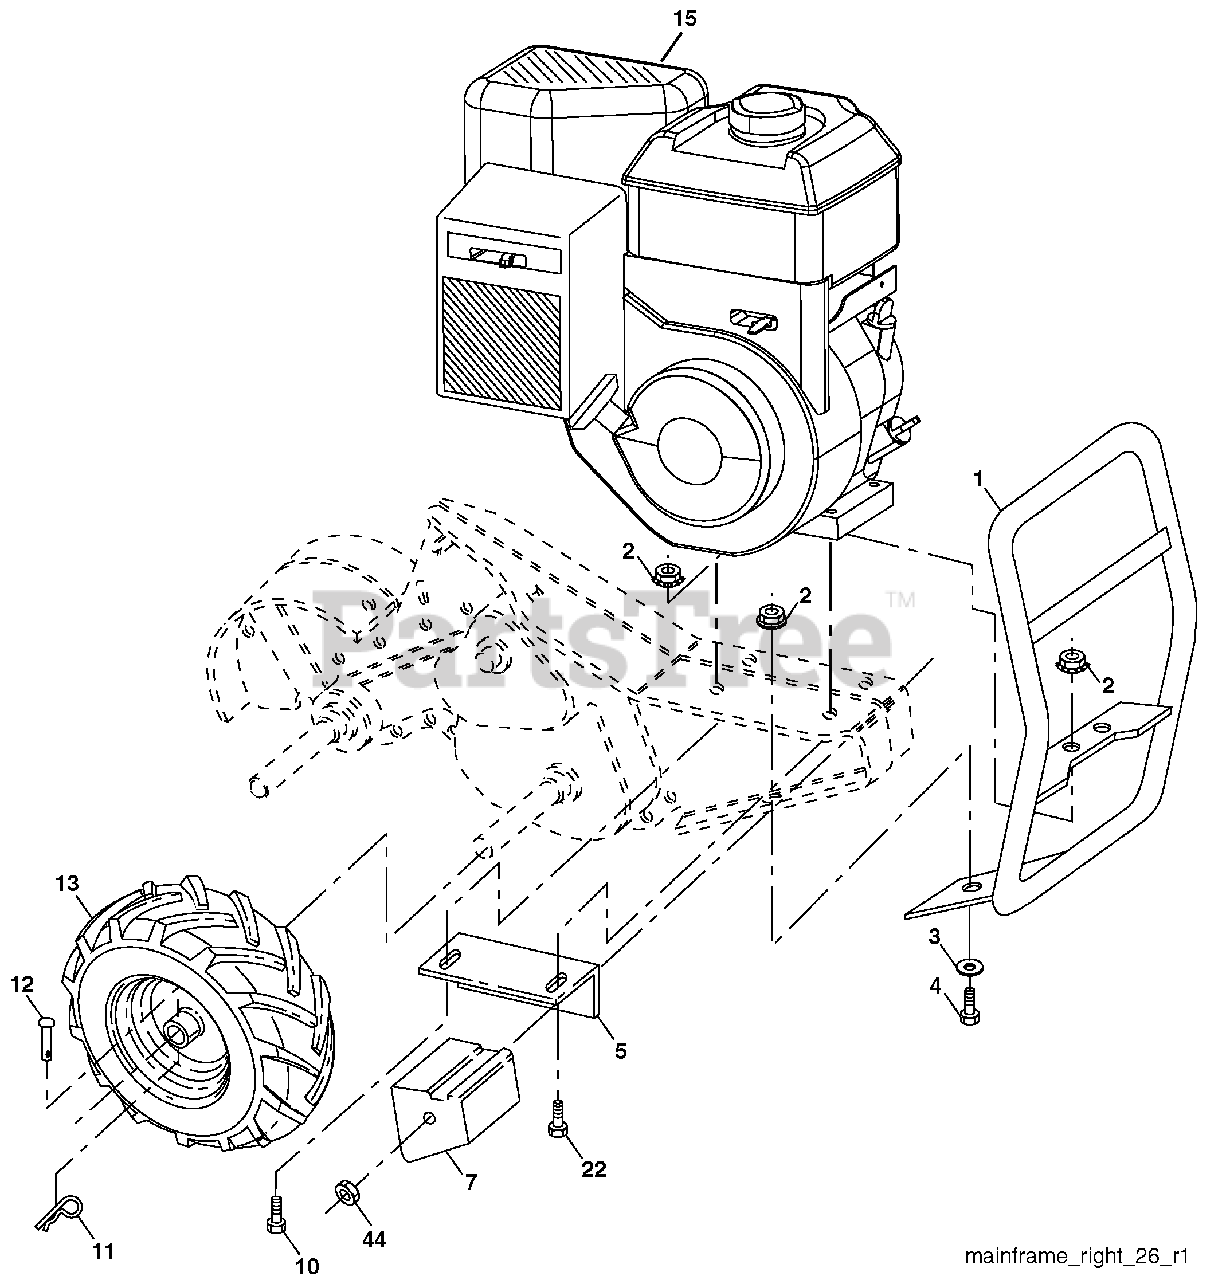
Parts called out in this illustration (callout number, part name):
2	Locknut, Hex, Flange 5/16-18
3	Washer 11/32 x 11/16 x 16 Ga.
4	Bolt, Hex 5/16-18 x 3/4
5	Bracket, Reinforcement
7	Counter Weight, R.H.
10	Bolt, Hex 5/16-18 x 1-1/2
11	Clip, Hairpin
12	Rivet, Drilled
13	Tire
13	Rim
13	Tire Valve
22	Bolt, Hex 5/16-18 x 1-3/4
44	Nut, Keps, Hex 3/8-16 unc
